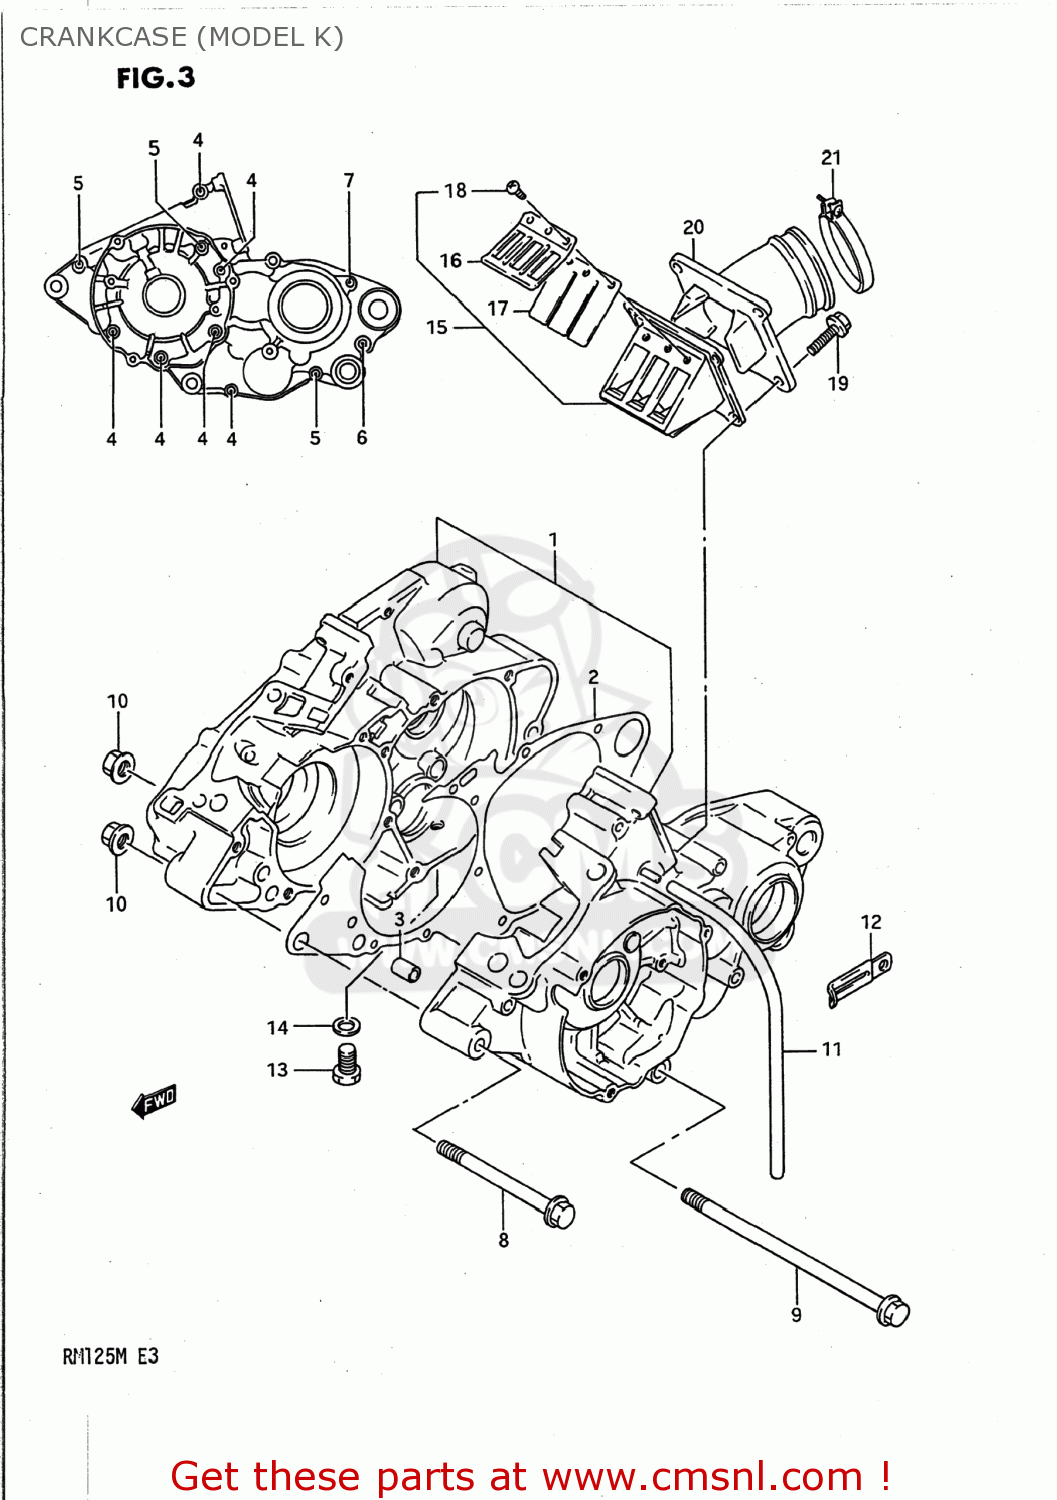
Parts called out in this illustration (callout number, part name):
1	CRANKCASE SET
2	GASKET,CRANKCASE (NAS)
3	PIN
4	BOLT
5	BOLT
6	BOLT
7	BOLT
8	BOLT 8X90
9	BOLT(8X150)
10	NUT
11	HOSE(4X7X600)
12	CLAMP L:35
13	BOLT,8X16
14	GASKET 8.2X14X1 (NAS)
15	VALVE ASSEMBLY,REED
16	STOPPER,REED VALVE
17	VALVE,REED
18	SCREW
19	BOLT
20	PIPE,INTAKE
21	CLAMP
